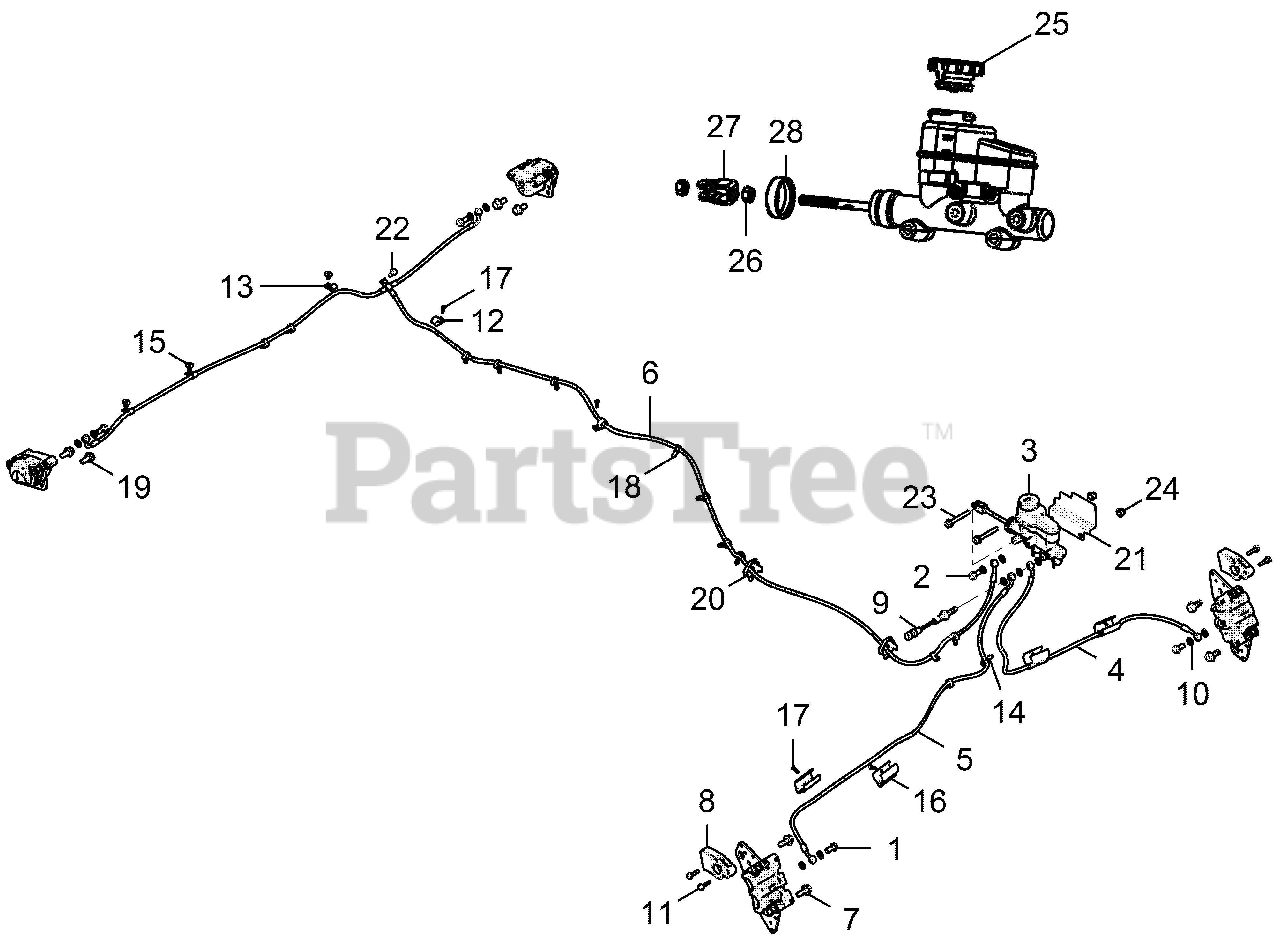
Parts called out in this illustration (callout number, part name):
1	BOLT-BANJO,10MMX1.00
2	BOLT-BANJO, 10MM X 1.25-6G
3	ASM-M/C-T,HBII,STD PUSH ROD
4	LINE-BRAKE,FRONT,LEFT,BRD
5	LINE-BRAKE,FRONT,RIGHT,BRD
6	LINE-BRK,3WAY,123",20B,90B,90B
7	BOLT-M10X1.25X25,HXFLG,W/PATCH
8	SCRAPER-BRAKE,FRONT
10	SEAL-STAT-O-3/8,70EP
12	CLAMP, CABLE
13	CLAMP,HOSE
14	CLIP-ROUTING
15	RIVET(50) *
16	RETAINER-BRAKE LINE,1"
17	POP RIVET(50)
19	BOLT-M10X1.25X20,HXFLG-OLV D
20	CLIP-ROUTING
21	SHIELD-MASTER CYL
22	SCR-M6X1.0X20,HXHD,FLG,TDFM,BL
23	SCR-HXFL-M8X1.25X60 8.8 ZOD
24	NUT-M8X1.25,FLG,NYLOC-OLIVE D
25	RESERVOIR CAP ASM.
26	NUT, HEX
28	#N/A
